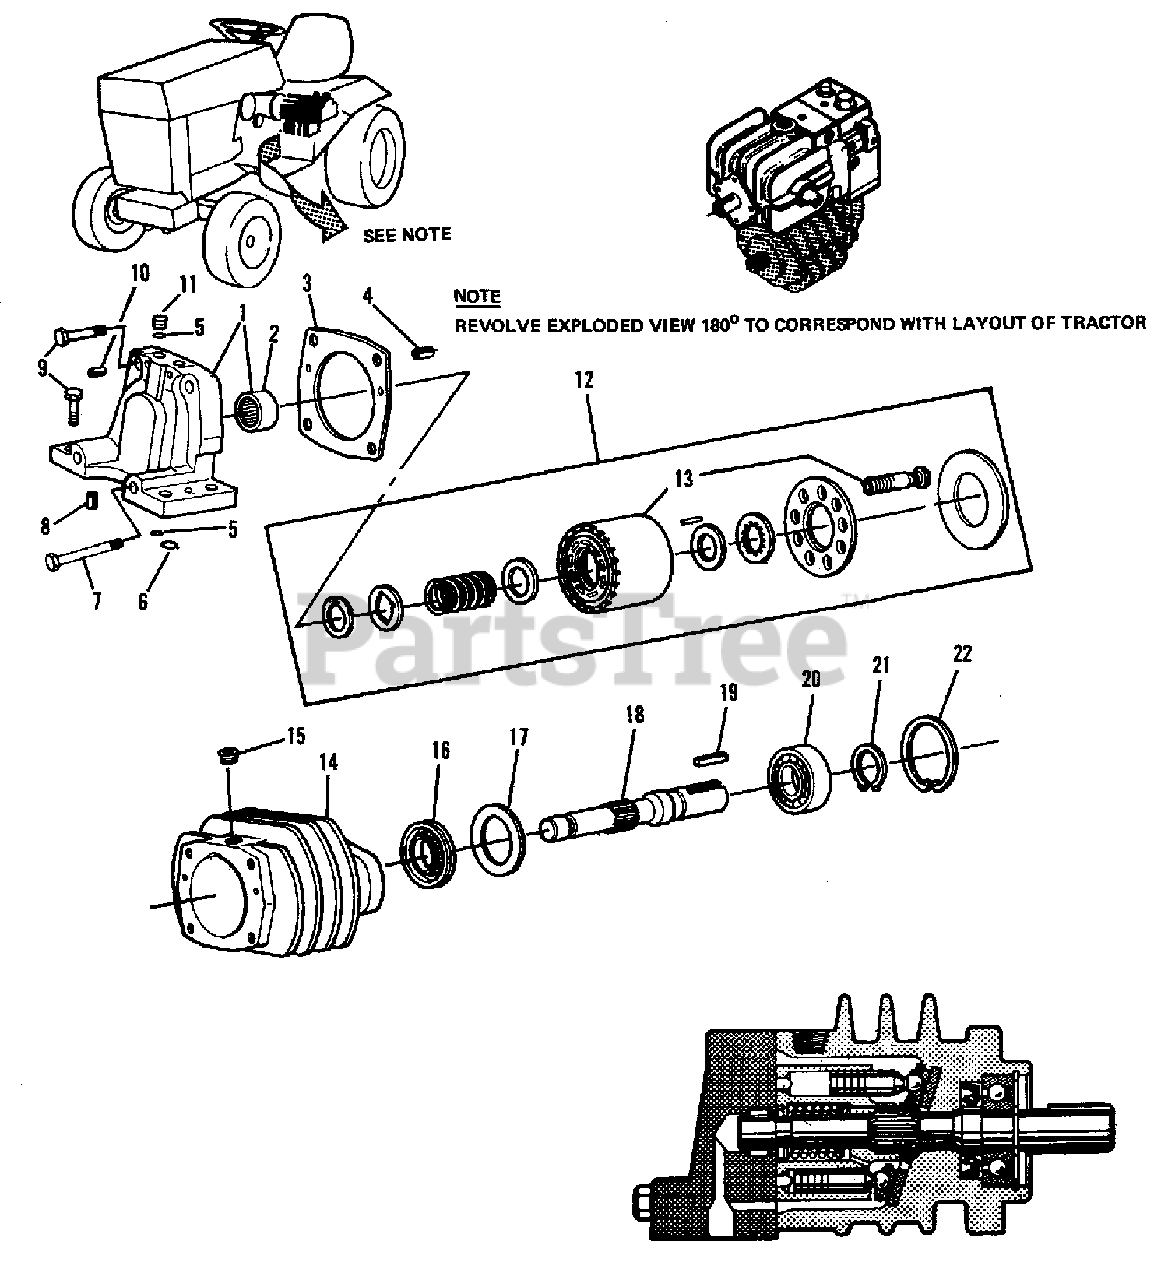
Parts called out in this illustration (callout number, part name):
1	PLATE ASSEMBLY, Valve (Includes Item 2)
2	BEARING, Needle
3	GASKET, Valve Plate
4	PIN, Dowel, 3/16 x 1/2
8	PIN, Dowel
12	MOTOR REPAIR KIT
13	CYLINDER REPAIR KIT (Includes PISTONS)
14	HOUSING, Motor
16	SEAL, Shaft
17	SPACER, Bearing
18	SHAFT, Motor
20	BEARING, Ball
21	RING, Snap
22	RING, Snap
